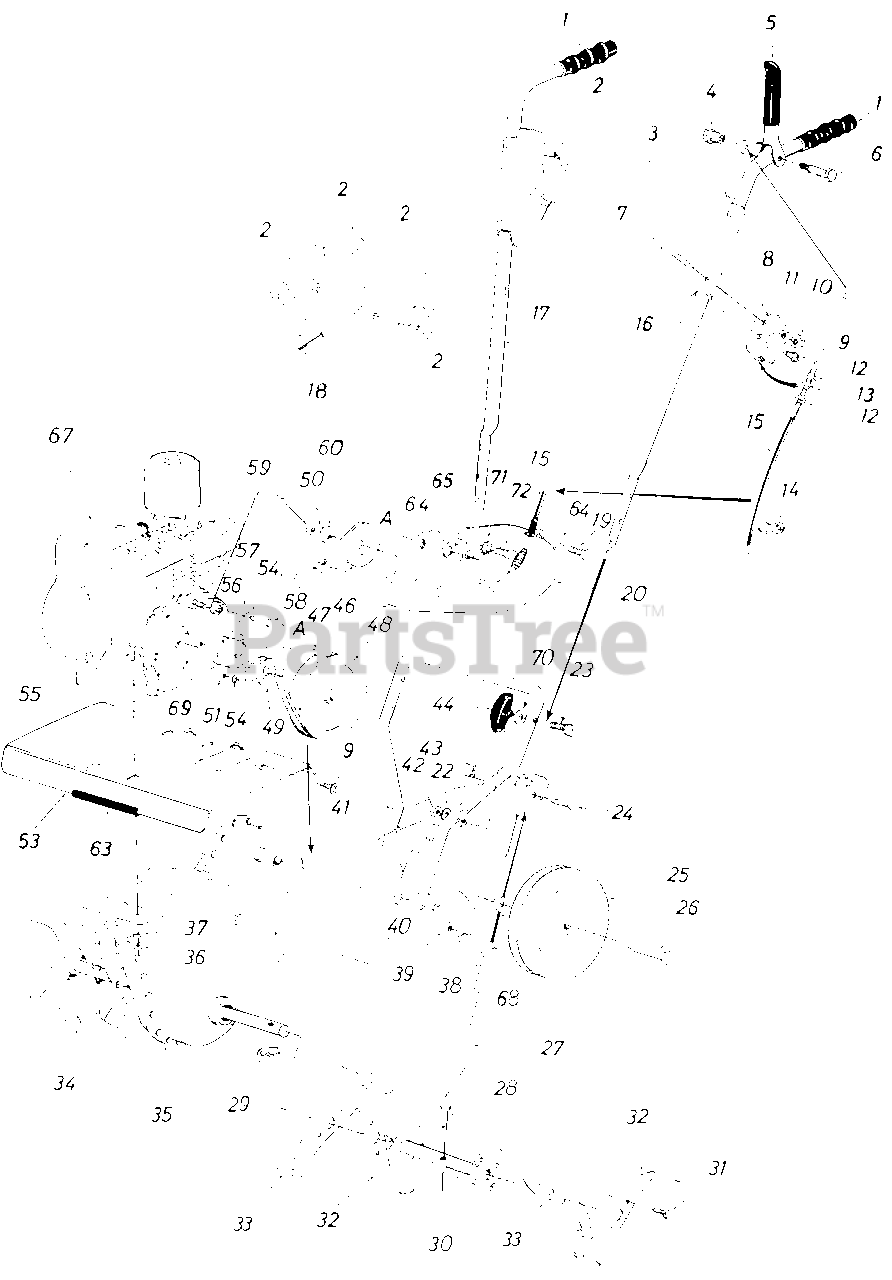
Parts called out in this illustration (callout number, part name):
2	Throttle Control Box Ass'y.
3	Handle Panel
4	Shoulder Nut
5	Clutch Grip Ass'y.
6	Shoulder Bolt 3/8 x 1.160" Lg.
7	Carriage Bolt 5/16-18 x 1.5" Lg.
8	Cable Support Bracket
9	Hex Wash. Hd. Self-Tap Scr. 1/4-20 x .50" Lg.
10	Hex Nut 5/16-18 Thd.
11	L-Wash 5/16" I.D.
12	Hex Jam Nut 5/16-24 Thd.
13	L-Wash. 5/16" I.D.
14	Cable Tie
15	Clutch Control Cable
19	Hex Bolt 1/4-20 x .75" Lg.
20	Belt Cover Ass'y.
22	L-Wash. 1/4" I.D.
23	Curved Hd. Bolt 5/16-18 x 1.75" Lg.
24	Clevis Pin
25	Wheel Ass'y. Comp. 7.0" x 1.5
26	Shoulder Bolt
29	Hairpin Cotter
36	Hex Nut 5/16-18 Thd.
37	L-Wash. 5/16" I.D.
38	L-Wash. 3/8" I.D.
39	Hex Cent. L-Nut 3/8-16 Thd.
40	Hex Wash. Hd. Self-Tap Scr. 5/16-18 x .50" Lg.
43	Internal Cotter Pin
44	Hand Knob
46	Idler Arm Ass'y.
47	Belt 3/8" x 29" Lg.
48	Chain Case Pulley 5-1/2 x 1/2"
49	Fl-Idler 2"
50	L-Wash. 5/16" I.D.
51	Hex Nut 3/8-24 Thd.
55	Hex Bolt 5/16-18 x 1.50" Lg.
56	Engine Pulley 3/8 V x .75 I.D. x 2" O.D.
57	Fl-Wash. .385" I.D. x 1.00"O.D.
58	H ex Bol t 3/8-24 x 1.00" Lg .
59	Hex Nut 5/16-18 Thd.
60	Shld. Spacer .50" Dia. x .133
63	Trim Strip-4"
64	Fl-Wash. .281" I.D. x .500"O.D.
65	Hex Cent. L-Nut 1/4-20 Thd.
67	Eng i ne
68	Bell-Wash.
69	Square Key 3/16 x 3/4" Lg.
70	Bell-Wash.
71	Ext. L-Wash. 1/2" I.D.
72	Hex Bolt 1/2-20 x .75" Lg.
